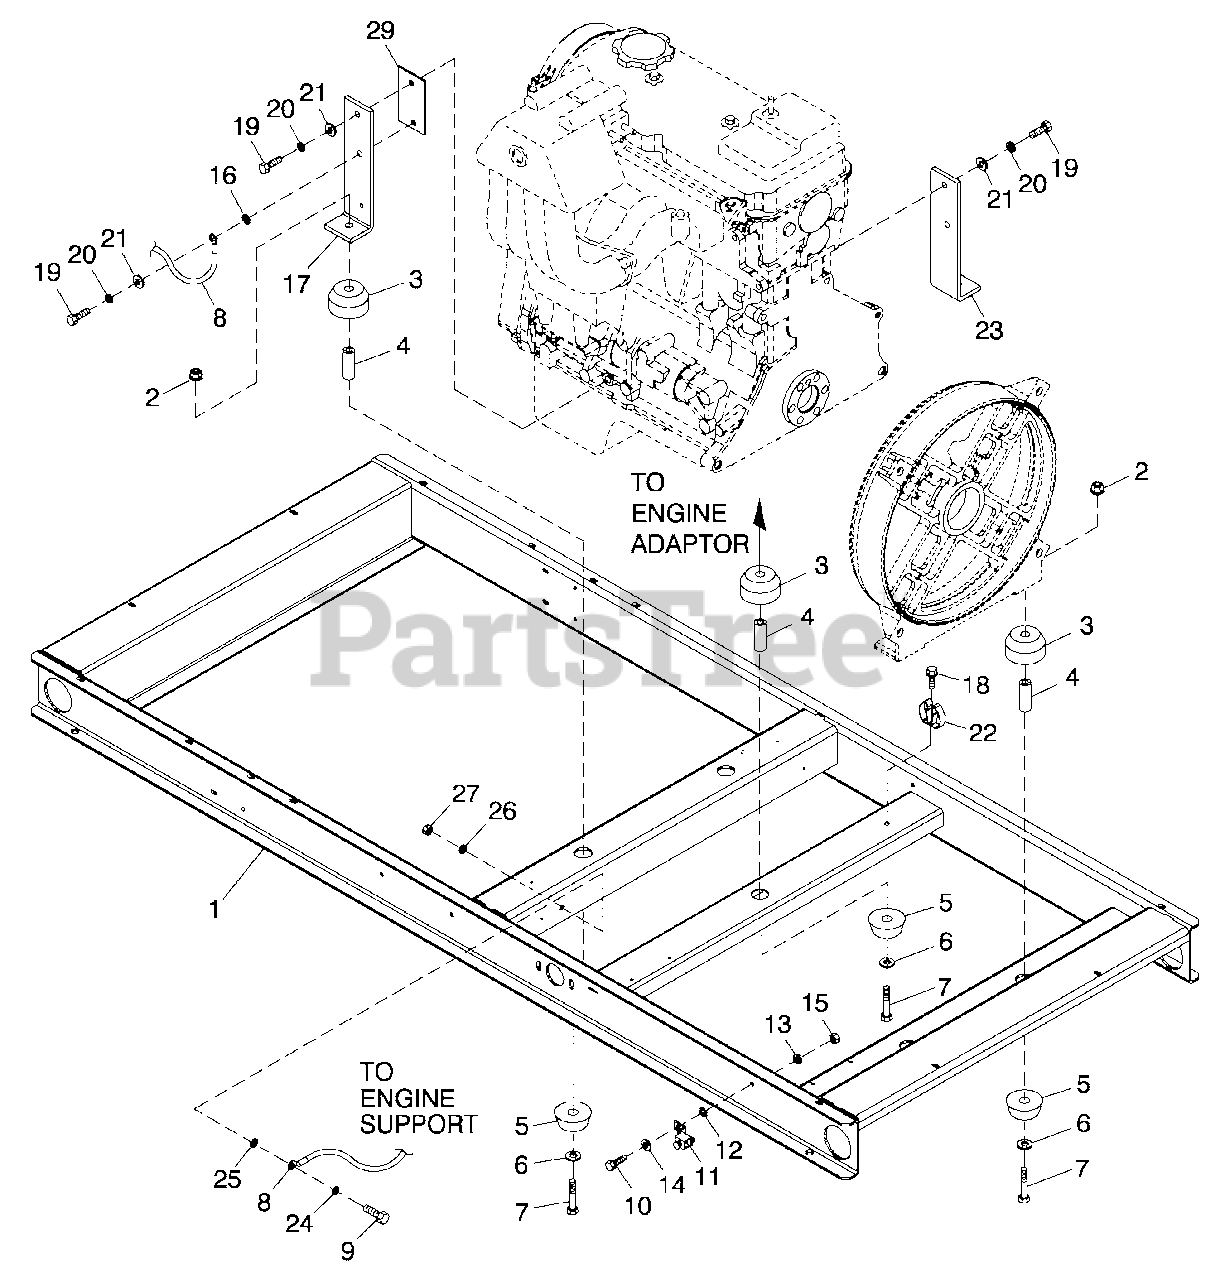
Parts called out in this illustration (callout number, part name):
1	WELDMENT FRAME 2.4L C2
2	NUT FLANGED HEX M12-1.75
3	DAMPENER VIBRATION 40 BLUE
4	SPACER .49 X .62 X 1.87 PWDR/ZNC
5	DAMPENER VIBRATION
6	WASHER FLAT M12
7	SCREW HHC M12-1.75 X 80 G8.8
8	ASSY WIRE 14.00"
9	SCREW HHC M8-1.25 X 30 G8.8
10	SCREW HHC M6-1.0 X 16 G8.8
11	LUG SLDLSS #2-#8 X 17/64 CU
12	WASHER SHAKEPROOF INT 1/4
13	WASHER LOCK M6-1/4
14	WASHER FLAT M6-1/4 ZINC
15	NUT HEX M6 -1.0 G8 YEL CHR
16	WASHER SHAKEPROOF INT 3/8
17	SUPPORT LH ENGINE 2.4L
18	SCREW HHTT M4-0.7 X 8 BP
19	SCREW HHC M10-1.25 X 30 G8.8
20	WASHER LOCK 7/16
21	WASHER FLAT 3/8-M10 ZINC
22	SPRING CLIP HOLDER .37-.62
23	SUPPORT RH ENGINE 2.4L
24	WASHER LOCK M8-5/16
25	WASHER SHAKEPROOF INT 5/16
26	WASHER FLAT 5/16-M8 ZINC
27	NUT HEX M8-1.25 G8 CLEAR ZINC
29	SPACER ENGINE MOUNT (2.4L G1)
